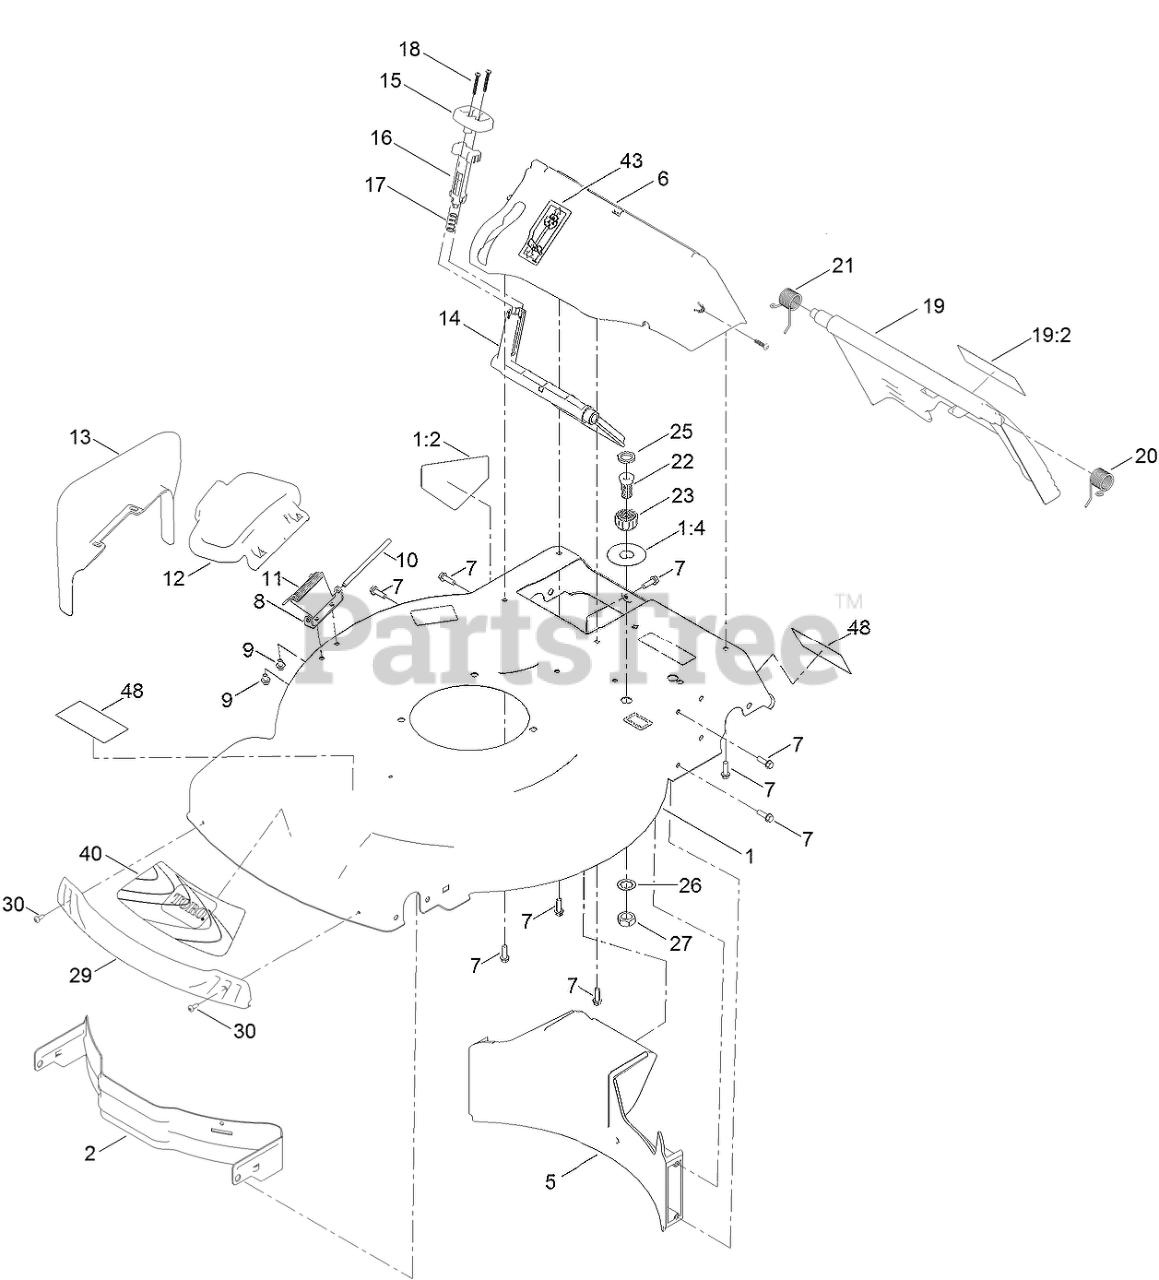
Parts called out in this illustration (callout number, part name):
1	HOUSING ASM
1:2	DECAL-DANGER
1:4	DECAL-QUICK WASH
2	BAFFLE-FRONT
5	BAFFLE-REAR
6	CHUTE-RECYCLE
7	SCREW-HWH
8	BRACKET-COVER
9	SCREW-HWH
11	SPRING-TORSION
12	DEFLECTOR-SIDE
13	CHUTE-DISCHARGE, SIDE
14	DEFLECTOR-RECYCLE
15	KNOB-RECYCLE
16	LATCH-RECYCLE
17	SPRING-COMPRESSION
18	SCREW-PPH
19	REAR DOOR ASM
19:2	DECAL-WARNING
20	SPRING-TORSION
21	SPRING-TORSION
22	PORT-WASHOUT
23	COUPLING-HOSE, WASHOUT PORT
25	WASHER-SEAL, WASHOUT PORT
26	WASHER-LOCK
27	NUT-JAM
29	BUMPER
30	SCREW-FORMING, THREAD
40	DECAL-RECYCLER
48	DECAL-TOOL, THD
